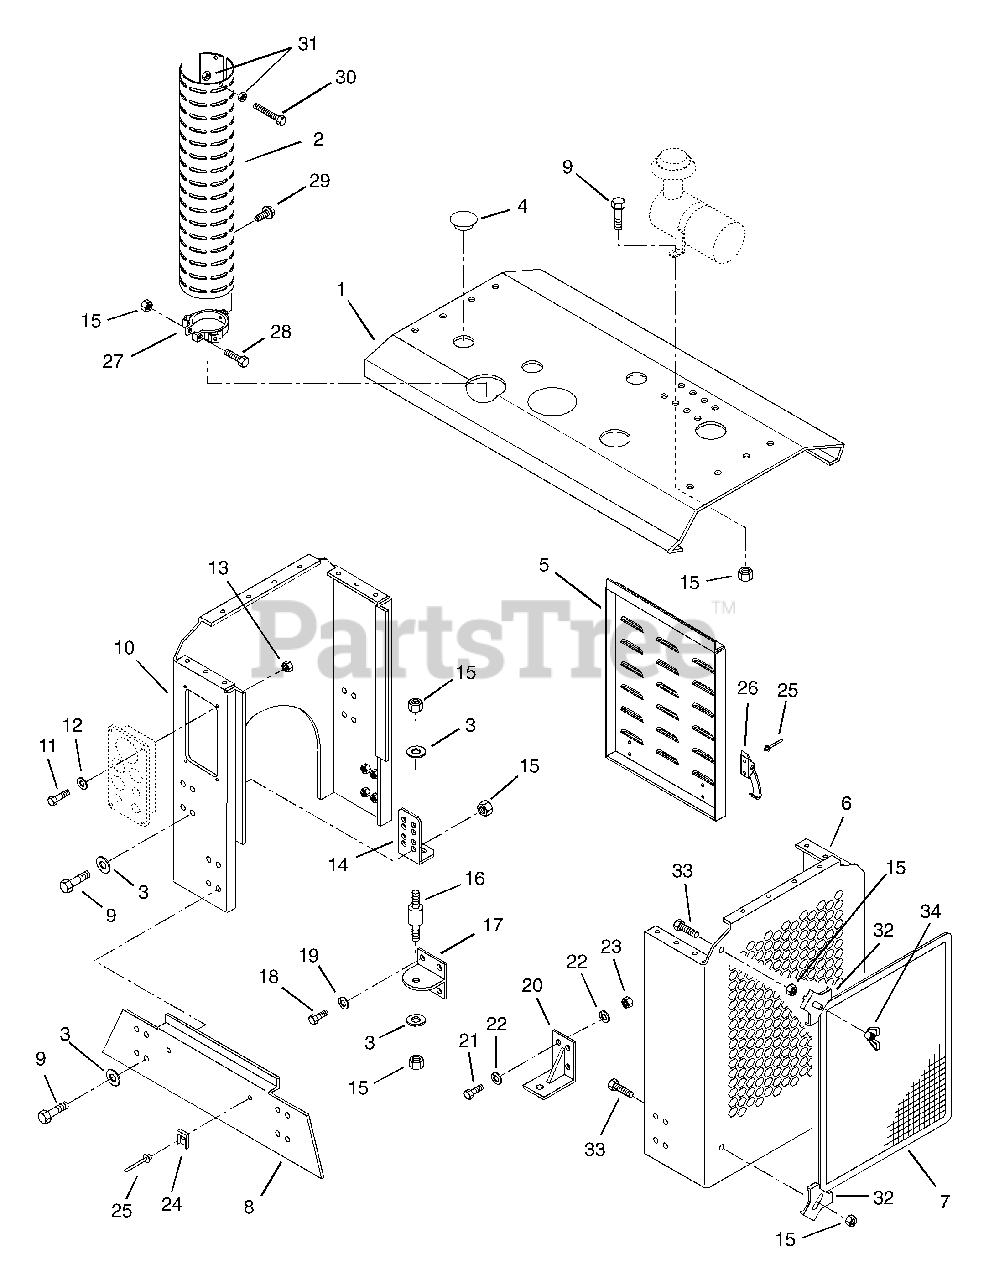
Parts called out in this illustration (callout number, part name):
1	Hood-81HP with Donaldson Air Cleaner
1	Hood-99HP with Donaldson Air Cleaner
1	Hood-108HP with Donaldson Air Cleaner
1	Hood-86HP
1	Hood-110HP
1	Hood-115 HP
2	Guard-Muffler
3	Washer-Flat-Steel .38 x .875 x .083
4	Hole Plug
5	Door
6	Front Panel
7	Radiator Screen
8	Side Filler Panel
8	Side Filler Panel-Right Hand
8	Side Filler Panel-Left Hand
9	Bolt-Hex .31-18 x .75 Grade 5
10	Rear Panel
11	Bolt-Hex .25-20 x 1.00 Grade 5
12	Washer-Flat-Steel .312 x .734 x .065
13	Nut-Lock-Center .25-20
14	Outer Support Bracket
15	Nut-Lock-Center .31-18
16	Isolator
17	Inner Support Bracket
18	Bolt-Hex .50-13 x 1.00 Grade 5
19	Washer-Lock .50 x .125
20	Inner Support Bracket
21	Bolt-Hex .38-16 x 1.00 Grade 5
22	Washer-Flat-Steel .438 x 1.00 x .083
23	Nut-Locking-Center .38-16
24	Catch-Over Center Latch
25	Rivet-Pop-Dome Steel .187 x .277
26	Latch-Over Center
27	Clamp-Muffler Guard
28	Bolt-Hex .31-18 x 1.50 Grade 5
29	Screw-Tapping-Hex Washer Head .31-18 x .50
30	Bolt-Hex .25-20 x 2.50 Grade 5
31	Nut-Locking-Center .25-20
32	Clip-Screen
33	Bolt-Hex .31-18 x 1.00 Grade 5
34	Nut-Wing-Nylon .312-18
